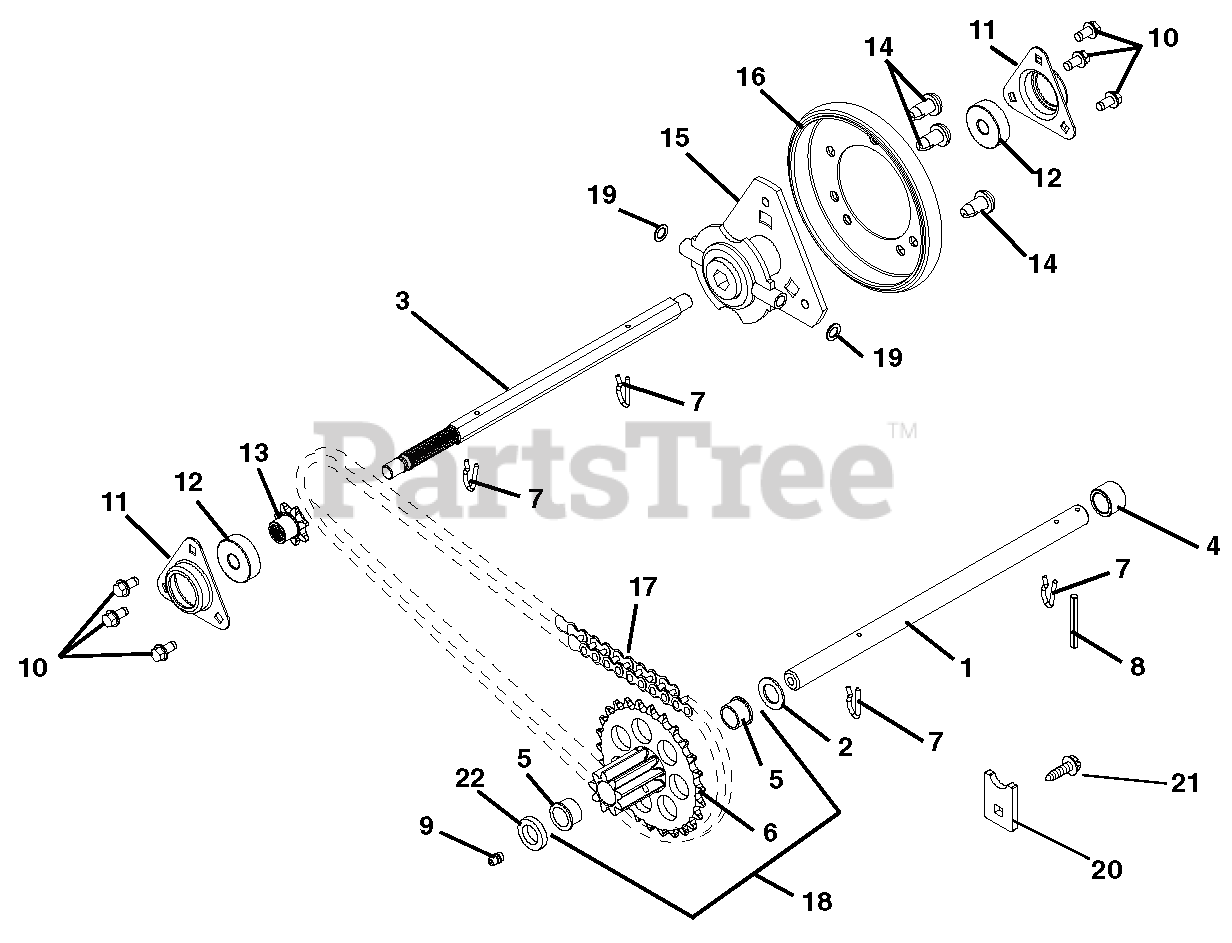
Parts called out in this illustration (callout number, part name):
1	Shaft, Pinion
2	Washer, Flat Steel .630 x 1.005 x .062
3	Shaft, Hex with Spline
4	Spacer .635 x .880 x .611
5	Bushing, Flange .625 x .750 x .500 x .875
6	Pinion and Sprocket
7	Pin, Spring Clip
8	Pin, Roll .125 x 1.00
9	Zerk, Fitting .25 x .125 Drive-In
10	Screw, Tapping Hex Washer Head .25-20 x .50
11	Flange, Bearing
12	Bearing, Ball .437 x 1.375 x .437
13	Sprocket, Pinion 7T with Spline
14	Screw, Serrated Head Tapping .31-18 x .50
15	Carrier, Drive Disk
16	Friction, Disk
17	Chain, #41, 32 Pitches
18	Pinion and Sprocket with Bushings
19	Washer, Flat-Steel .505 x 1.00 x .062
20	Tab, Antirotation (serial number 000301 & up)
21	Screw, Tapping .25-20 x .50
22	Bushing, Sleeve, .635 x .880 x .305
